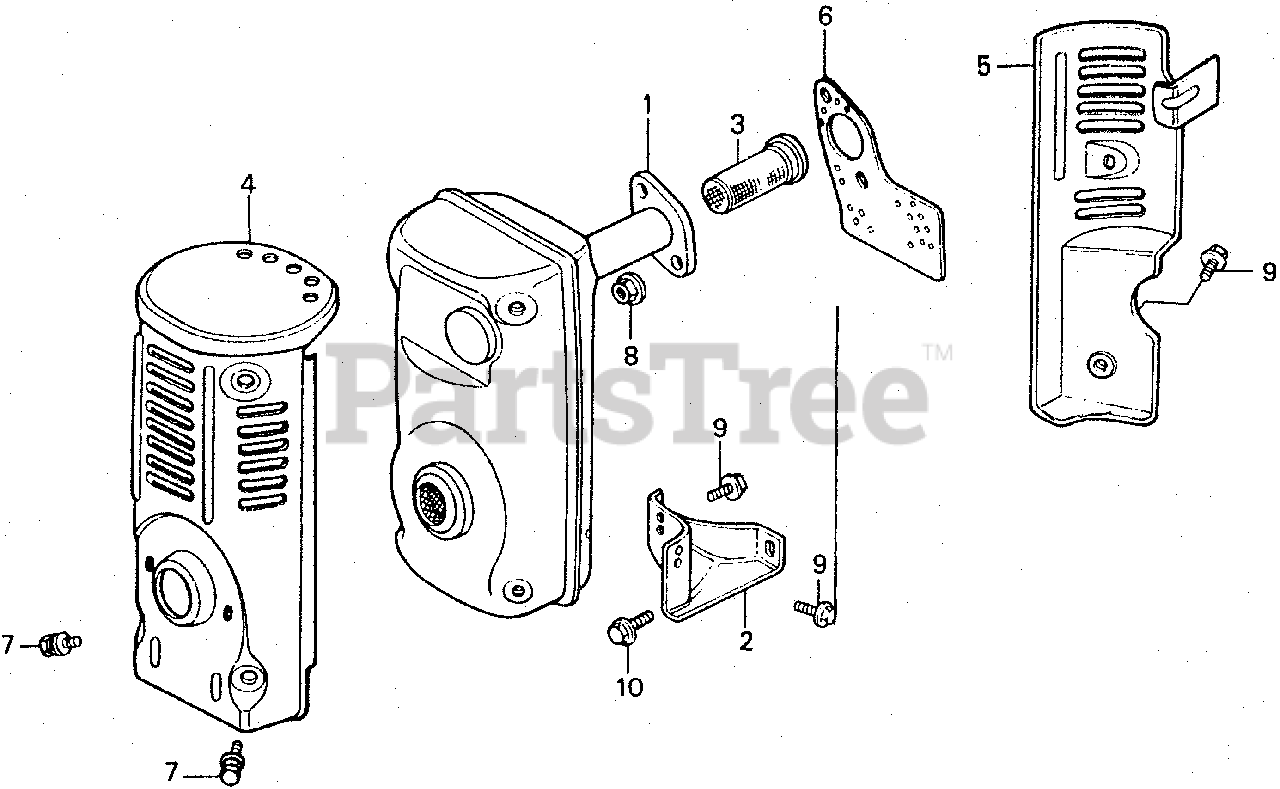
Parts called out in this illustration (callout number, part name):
1	MUFFLER (ARRESTER)
1	MUFFLER
2	STAY, MUFFLER
3	ARRESTER, SPARK
4	PROTECTOR A, MUFFLER
5	PROTECTOR B, MUFFLER
6	GASKET, MUFFLER
7	BOLT-WASHER (6X10)
7	BOLT, HEX. (6X8)
8	NUT, FLANGE (8MM)
9	BOLT, FLANGE (6X10)
10	BOLT, FLANGE (8X14)
10	BOLT, FLANGE (8X16)
